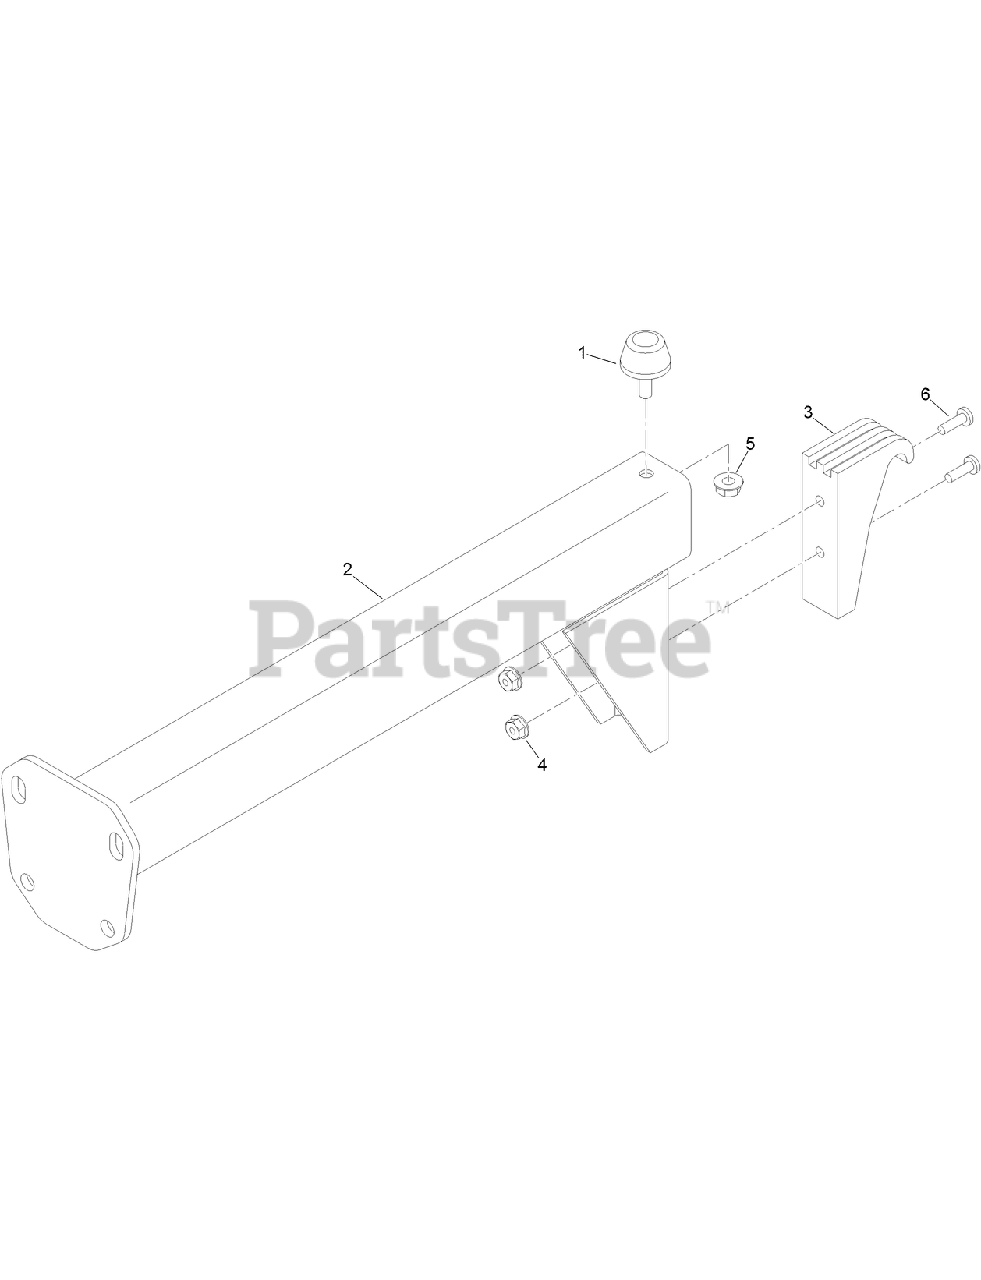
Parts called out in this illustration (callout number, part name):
1	BUMPER
2	SUPPORT-BAG
4	NUT-HF
5	NUT-HF
6	SCREW-PPH
